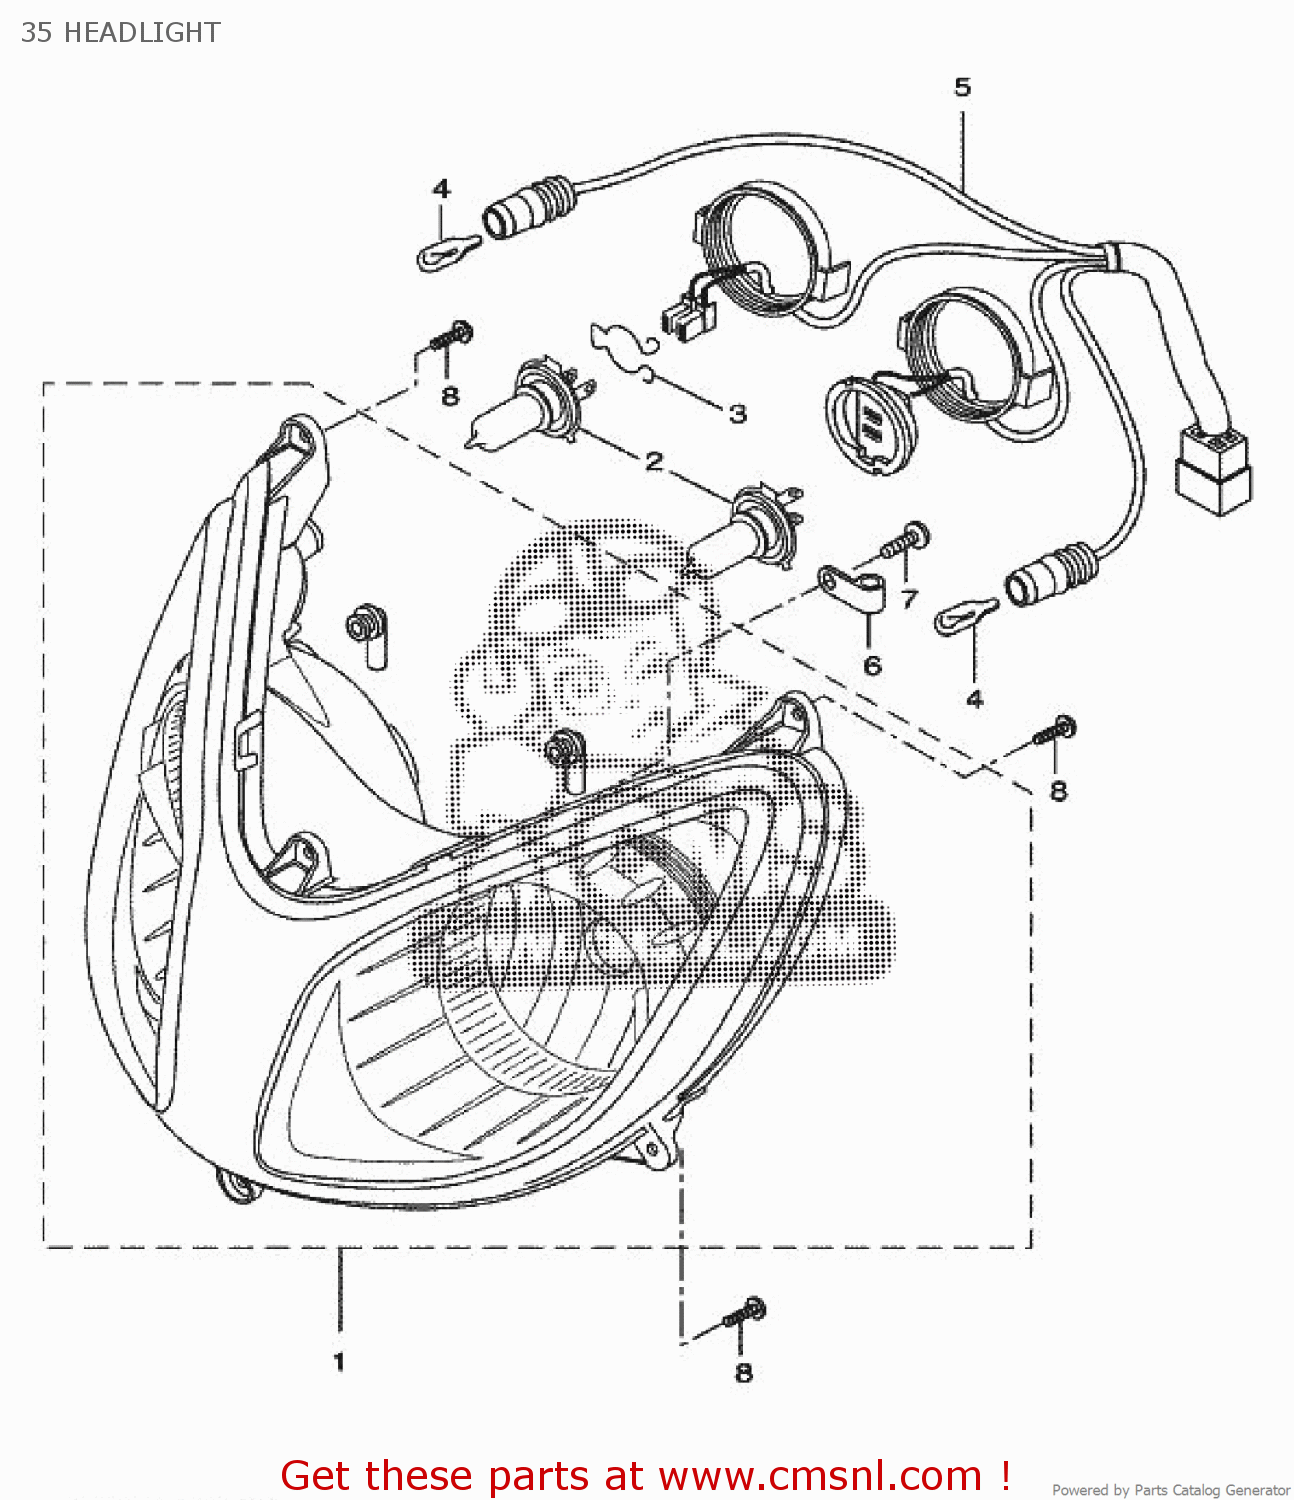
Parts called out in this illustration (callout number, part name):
1	HEADLIGHT UNIT ASSY
2	BULB, HEADLIGHT
3	SPRING SET
4	BULB LICENCE LIGHT
5	SOCKET CORD ASSY
6	CLIP
7	SCREW
8	SCREW, TAPPING
